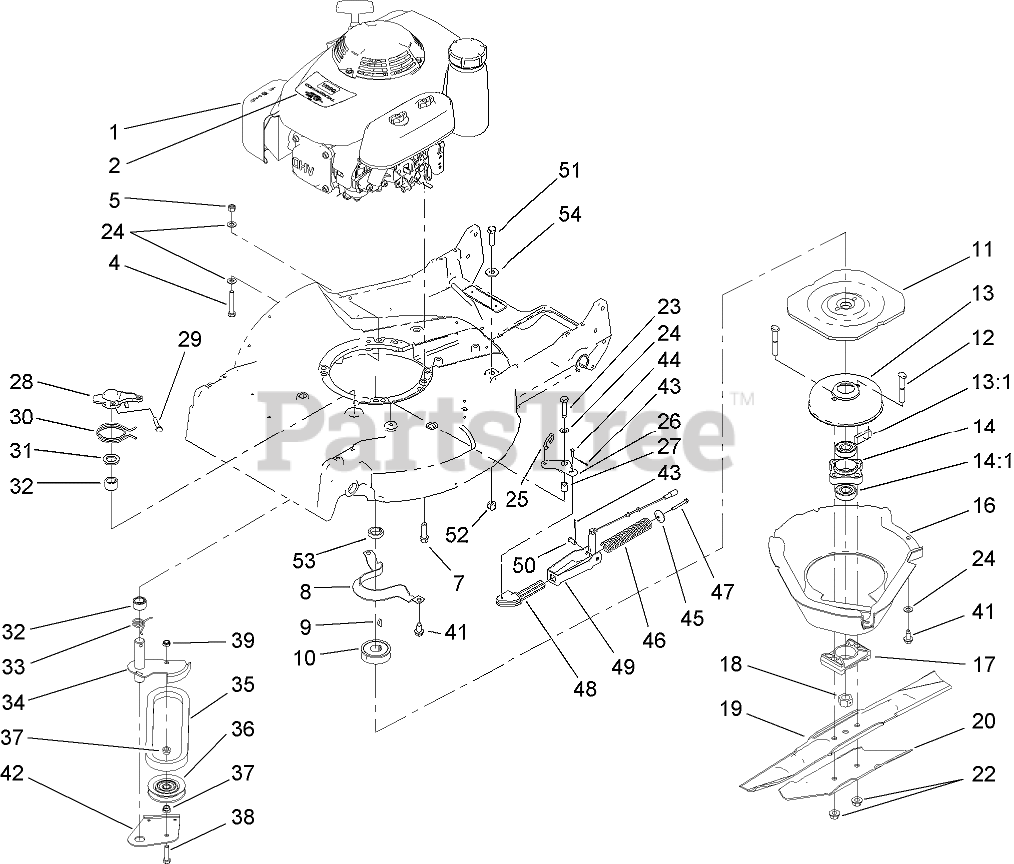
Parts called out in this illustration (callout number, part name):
1	Engine ASM
2	DECAL-ENGINE, HONDA
4	SCREW-HH
5	NUT-LOCK, NI
7	SCREW-SHOULDER
8	BRACKET-GUIDE, BELT
9	KEY-WOODRUFF
10	PULLEY-DRIVER
11	FLYWHEEL-BBC
12	BOLT-BLADE
13	BRAKE DRUM ASM
13:1	DAMPENER-VIBRATION
14	HUB ASM
14:1	BEARING-BALL
16	SHIELD
17	SPACER-BLADE
18	NUT-BLADE
19	BLADE-21 INCH
20	STIFFENER-BLADE
22	NUT-LOCK
23	SCREW-HH
24	WASHER-PLAIN
25	LINK-CONTROL
26	BELLCRANK
27	SLEEVE-BELLCRANK
28	LEVER
29	SCREW-HH
30	SPRING-TORSION
31	WASHER
32	BEARING
33	SPRING-TORSION
34	ARM-IDLER
35	V-BELT
36	PULLEY-IDLER
37	SPACER-PULLEY, IDLER
38	SCREW-HH
39	NUT-LOCK, NI
41	SCREW-HWHTF
42	BRAKE PLATE ASM
43	PIN-COTTER
44	PIN-SPRING
45	RETAINER-SPRING
46	SPRING
47	SCREW-HWHTF
48	GUIDE-SPRING
49	BRACKET-SPRING
50	PIN-CABLE
51	SCREW-HH
52	NUT-LOCK, NI
53	SPACER-PULLEY
54	WASHER-HARDENED
